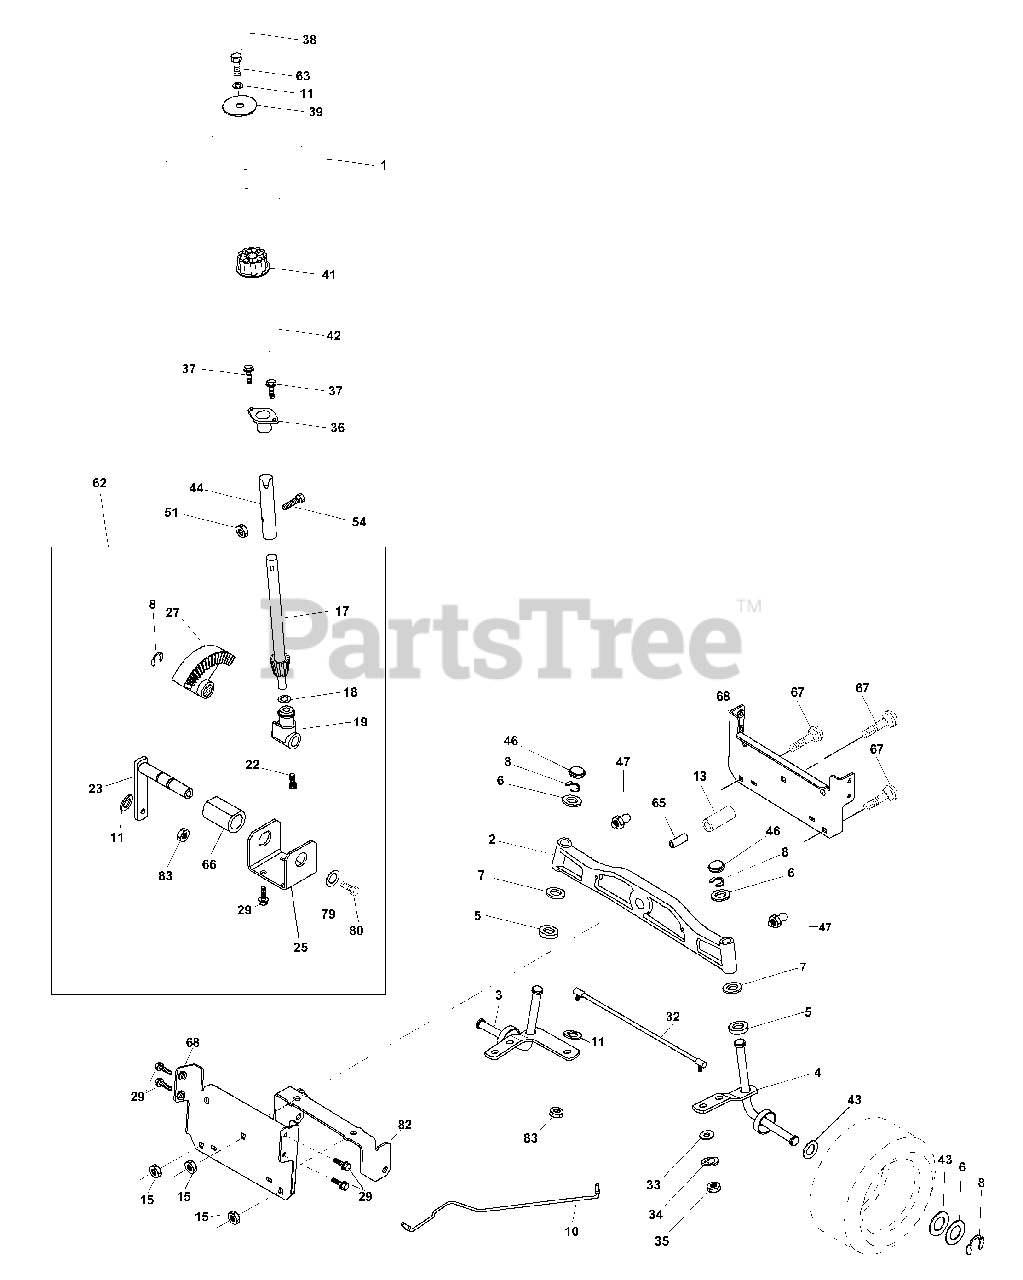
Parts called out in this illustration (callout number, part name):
1	Steering Wheel
2	Axle, Front
3	Spindle, L.H.
4	Spindle, R.H.
5	Bearing, Thrust
6	Washer 25/32 x 1-5/8 x 16 Gauge
7	Washer 27/32 x 1-1/4 x 16 Ga.
10	Link, Drag
11	Washer, Lock 3/8
12	Nut, Hex, Jam, Top Lock 1/2-20 UNF
13	Spacer Brg Axle front
15	Nut Hex flange Lock Yel D
17	Shaft, Steering
19	Shaft, Support
22	Screw Hex Wsh hd Torx
23	Shaft, Pitman
25	Bracket, Steering
27	Gear, Sector
29	Screw, 3/8-16 x 3/4
32	Rod, Tie
33	Washer 11/32 x 3/4 x 16 Ga.
34	Washer Lock Hvy Helical 5/10 SD
35	Nut Crown Lock 5/16-18 Slvr DC
36	Bushing Steering
37	Screw TT #10-32 X 5 x 3/8 Flange
38	Insert, Steering Wheel
39	Washer
41	Adapter, Steering Wheel
42	Boot Steering Dash P/L Mtl
43	Washer, 25/32 x 1-1/4 x 16 Gauge
44	Extension Steering Non-Adjust
46	Spindle, Cap
47	Grease Zerk
51	Nut Crown Lock 5/16-18 Blk D
54	Bolt Fin Hex 5/16-18 Unc x 1-1/4
62	Kit Steering Asm Service
63	Bolt Fin Hex 3/8-16 Unc x 1 Gr. 5
65	Spacer Brace Axle
66	Bearing Arm Pittman
67	Bolt Rdhd Sqnk 3/8-16 x 2-1/4
68	Brace Brace Axle
79	Washer 13/32 x 1-1/4 x 12 Ga
80	Bolt Hex Nylon 3/8-16 x 3/4
82	Bracket Susp Chassis Front 15"
83	Nut, Lock Center 3/8-24 Unf Blk
